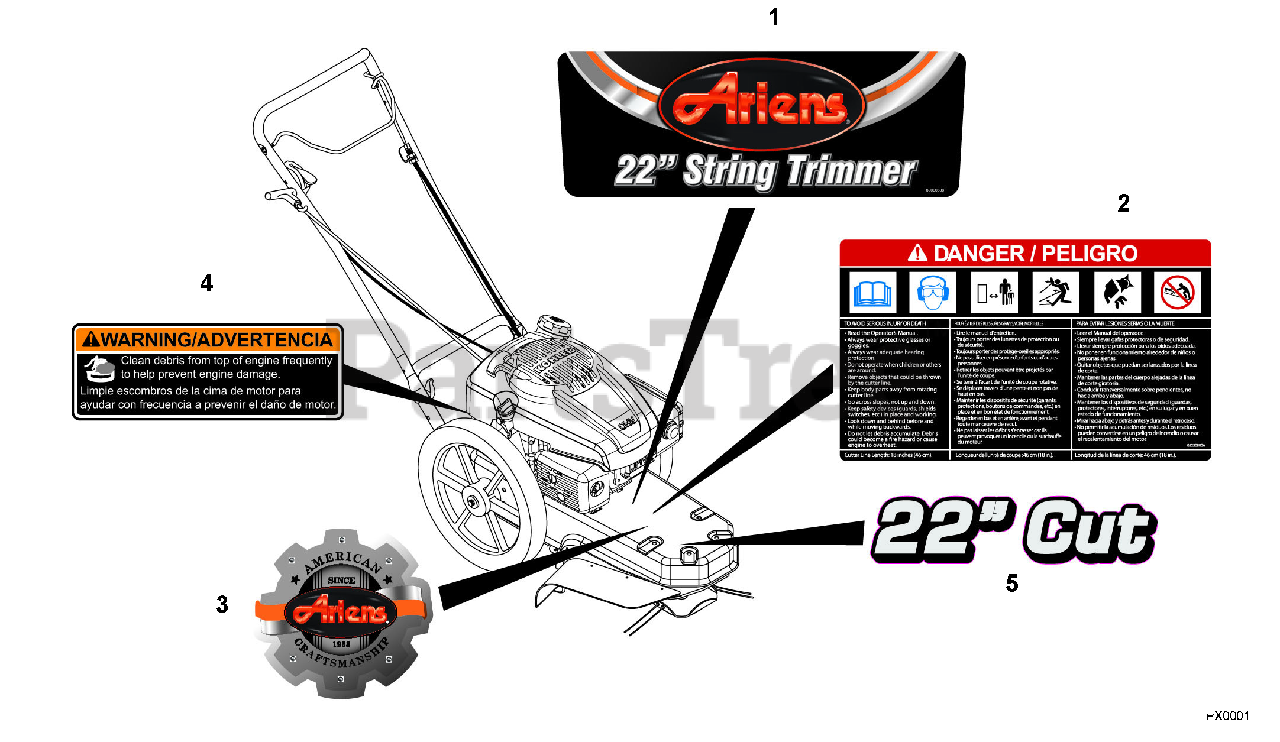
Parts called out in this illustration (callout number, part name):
1	DECAL, ARIENS STRING TRIMMER
2	DECAL - DANGER-STRING TRIMMER
3	Decal, Ariens Heritage
4	DECAL, TRIMMER DEBRIS WARNING
5	DECAL, 22" CUT(STRING TRIMMER)
